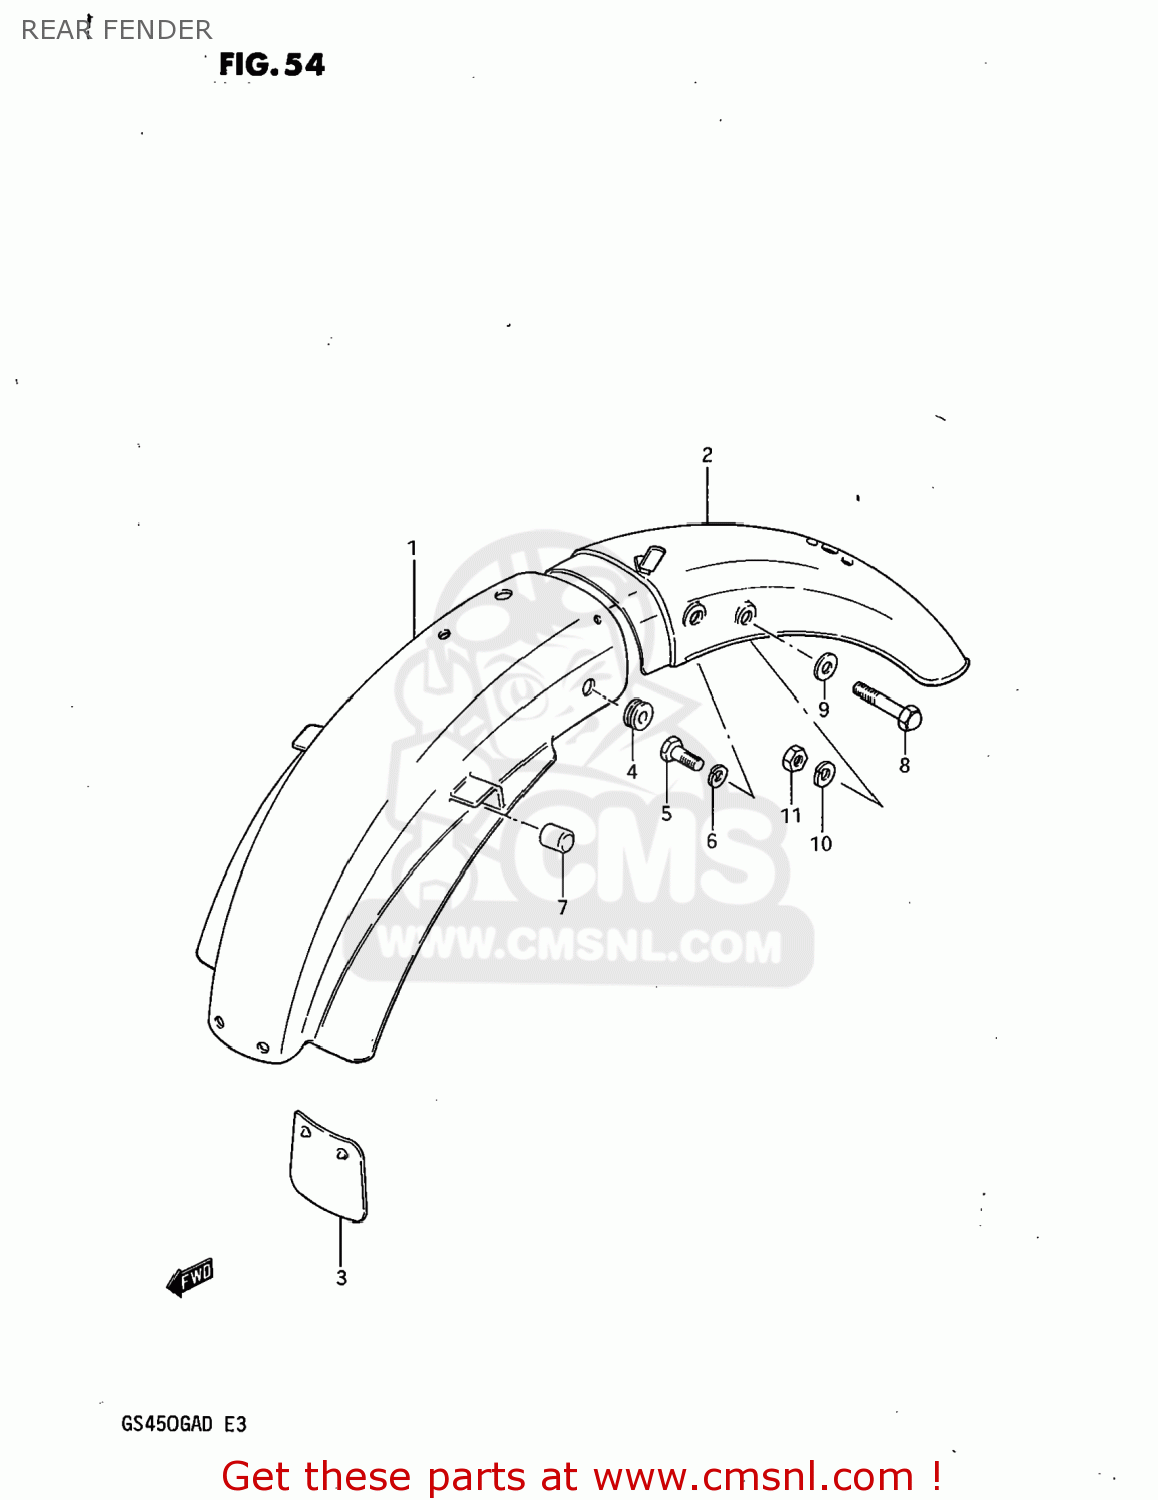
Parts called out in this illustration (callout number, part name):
1	BODY,REAR FENDER,FRONT
2	FENDER,REAR
3	GUIDE,RR FENDER MUD
4	CUSHION
5	BOLT 8X12
6	LOCK WASHER
7	CUSHION
8	BOLT
9	WASHER
10	LOCK WASHER
11	NUT
